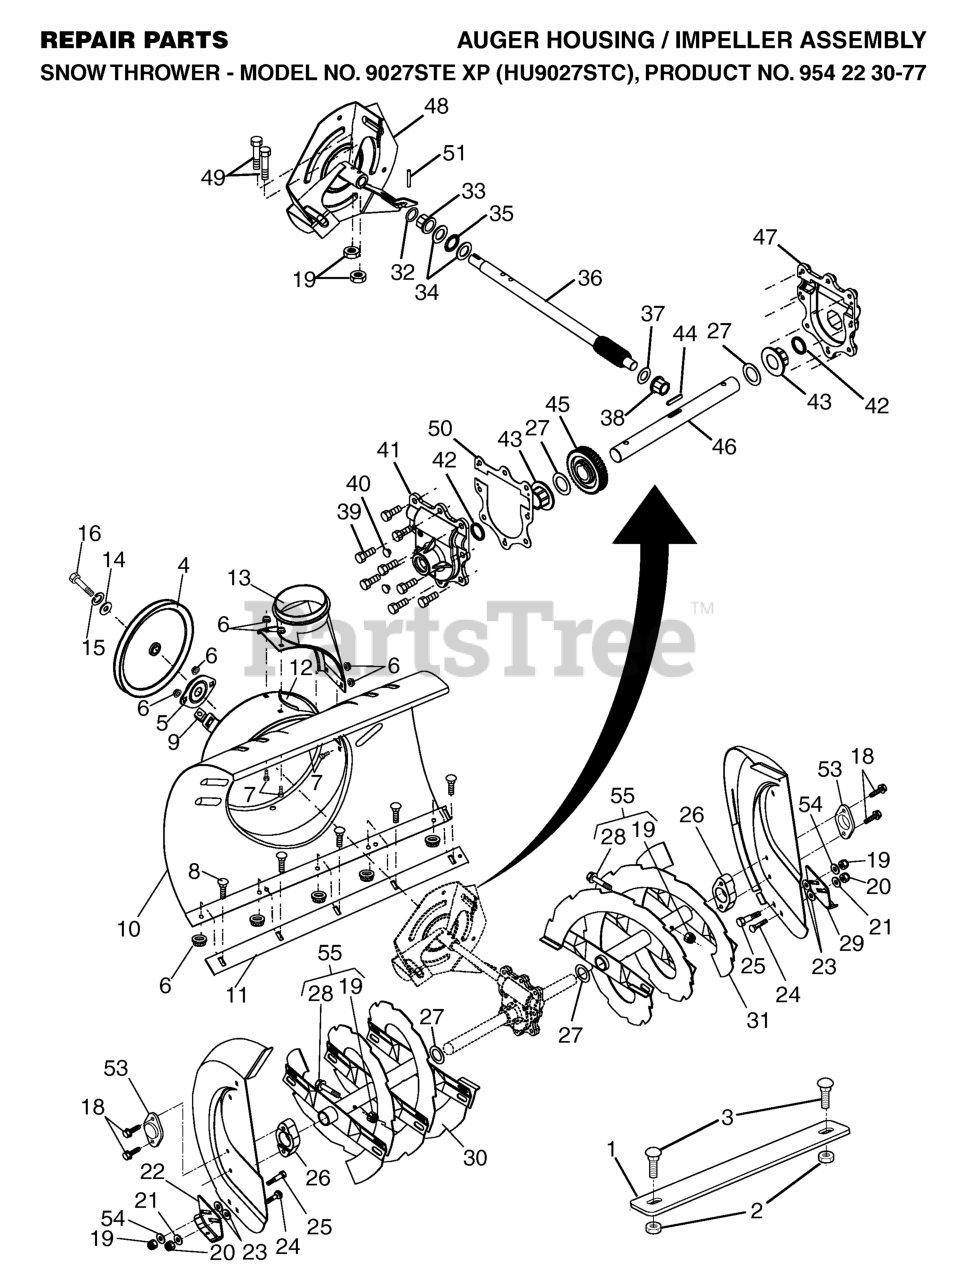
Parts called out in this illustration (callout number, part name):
1	WEIGHT, AUGER HOUSING 27
2	LOCKNUT 5/16-18
3	BOLT.CARRIAGE.5/16-18
4	PULLEY, IMPELLER
5	BEARING FLANGE
6	NUT.FLANGE.5/16
7	BOLT.CARRIAGE.5/16-18X
8	BOLT
9	NUT, CAGE 3/8-16
10	AUGER HOUSING WELDMENT
11	BAR, SCRAPER 27"
12	BRACKET, CORNER DISCHARGE
13	BASE DISCHARGE CHUTE
14	WASHER, FLAT
15	WASHER.LOCK.HVY.HLCL.SPR.5/16
16	Screw, Hex Head 5/16-18 x 3/4
18	SCREW, HEX HD 5/16X1
19	LOCKNUT.NYLOC.1/4-20
20	NUT.71038.31-18.HEX.NYLOCK
21	WASHER.20X8.5
22	SKID PLATE RH
23	WASHER, NYLON FRICTION
24	BOLT
25	SHOULDER BOLT
26	BEARING RETAINER, PLASTIC
27	WASHER TRUST 1"
28	BOLT.SHOULDER.SHEAR.1/4-20.
29	SKID PLATE LH
30	AUGER ASM 27" RH
31	AUGER ASM 27" LH
33	BUSHING FLANGE 3/4
34	WASHER, THRUST 3/4
35	BEARING TRUST 3/4 NTA-1220
36	SHAFT, IMPELLER
37	WASHER, THRUST 5/8
38	BUSHING.FLANGE.(.625X.75)
39	SELF-TAPPING SCREW 5/16-18X3/4
40	PLUG.AUGER.GEAR.BOX.SNOW
41	HOUSING.GEARBOX.RH.SNOW
43	BUSHING FLANGE 1"
44	KEY, SQUARE 1/4 X .875
45	WORM GEAR
46	SHAFT, AUGER
47	LH GEARBOX HOUSING
48	IMPELLER ASSY
49	SCREW.HEX.HD1/4-20X
50	GASKET.AUGER.GEARBOX
51	PIN, ROLL 3/16 X 1-1/8
53	BEARING.BALL.AUGER.SHAFT
54	WASHER
55	KIT, BOLT, SHEAR
